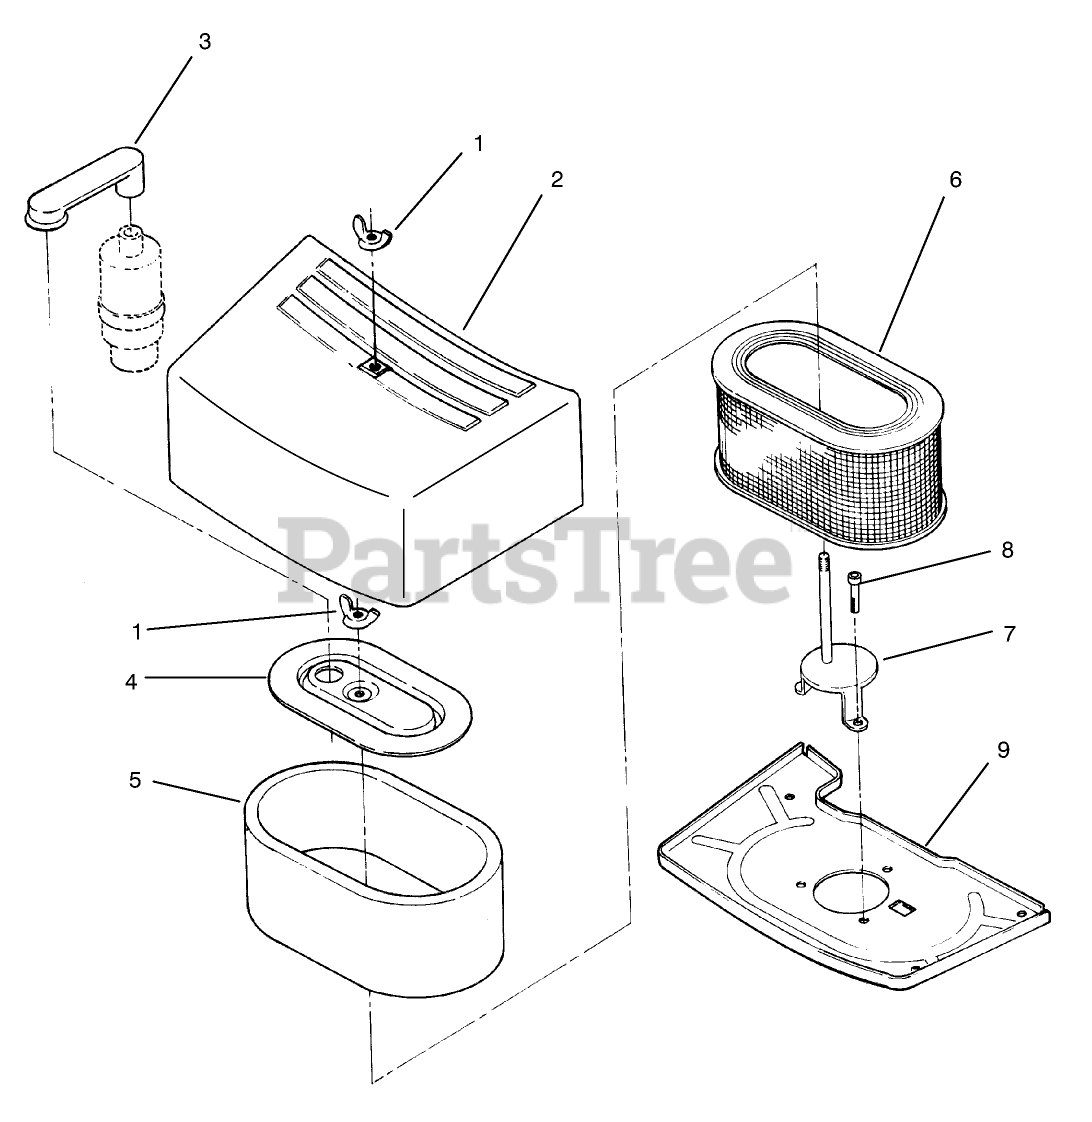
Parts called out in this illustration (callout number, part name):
1	Nut-Wing
3	BREATHER-TUBE
4	ELEMENT-COVER (ZINC)
5	ELEMENT-WRAPPER
6	ELEMENT
7	Support-Hood
8	SOCKET-HEAD CAP SCRW
9	PAN (ZINC)
